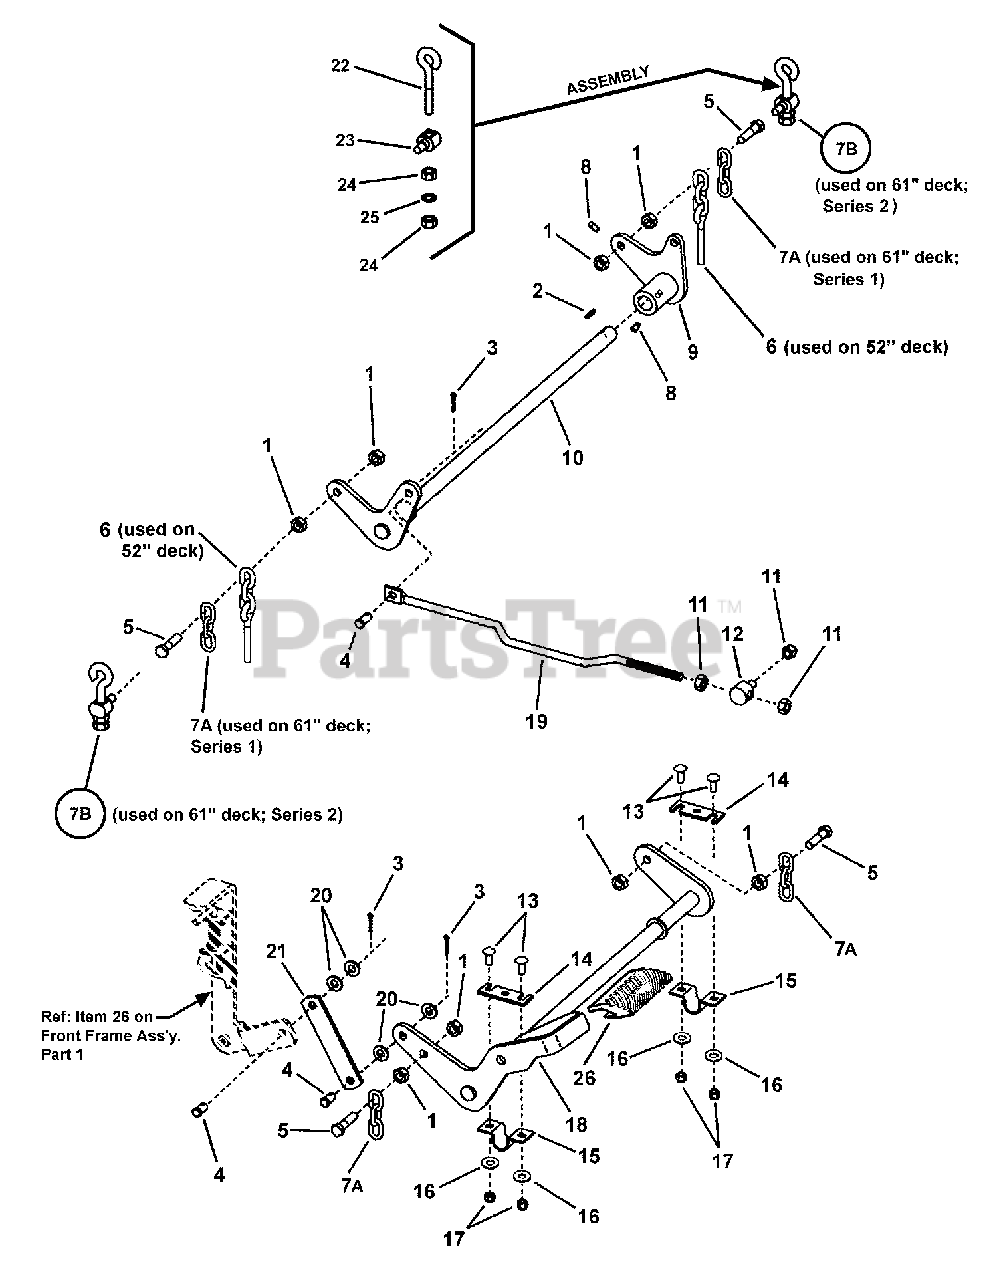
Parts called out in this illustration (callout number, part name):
1	NUT, 1/2-13 Hex Flange GR 5
2	KEY, 3/16" Square x 1-1/2"
3	PIN, 5/32 x 1" Cotter
4	PIN, 1/2 x 1-1/8" Clevis
5	SCREW, 1/2-13 x 2" Hex Head Cap, GR 5
6	ASSEMBLY, Chain & Eyebolt
7A	CHAIN, 3 Links
8	SET SCREW, 5/16-18 Square Head Cup Point
9	WELDMENT, Bellcrank Lift
10	WELDMENT, Rear Lift
11	NUT, 1/2-13 HEX SIDE LOCK
12	SWIVEL, Timing Rod (1/2-13 External Thread)
13	BOLT, 5/16-18 x 1" Short Neck Carriage, GR 5
14	SHIM PLATE
15	BRACKET, Deck Support
16	WASHER, 5/16" Flat
17	NUT, 5/16-18 HEX NYLON LOCK
18	WELDMENT, Front Deck Lift
19	ROD, Timing (1/2-13 Thread)
20	WASHER, .531 I.D. Flat
21	LINK, Front
22	ROD LINK (1/2-13 thread)
23	ROD SWIVEL (1/2-13 thread)
24	NUT, 1/2-13 HEX
25	WASHER, 1/2" Internal Tooth Lock
26	PEDAL, Rubber
